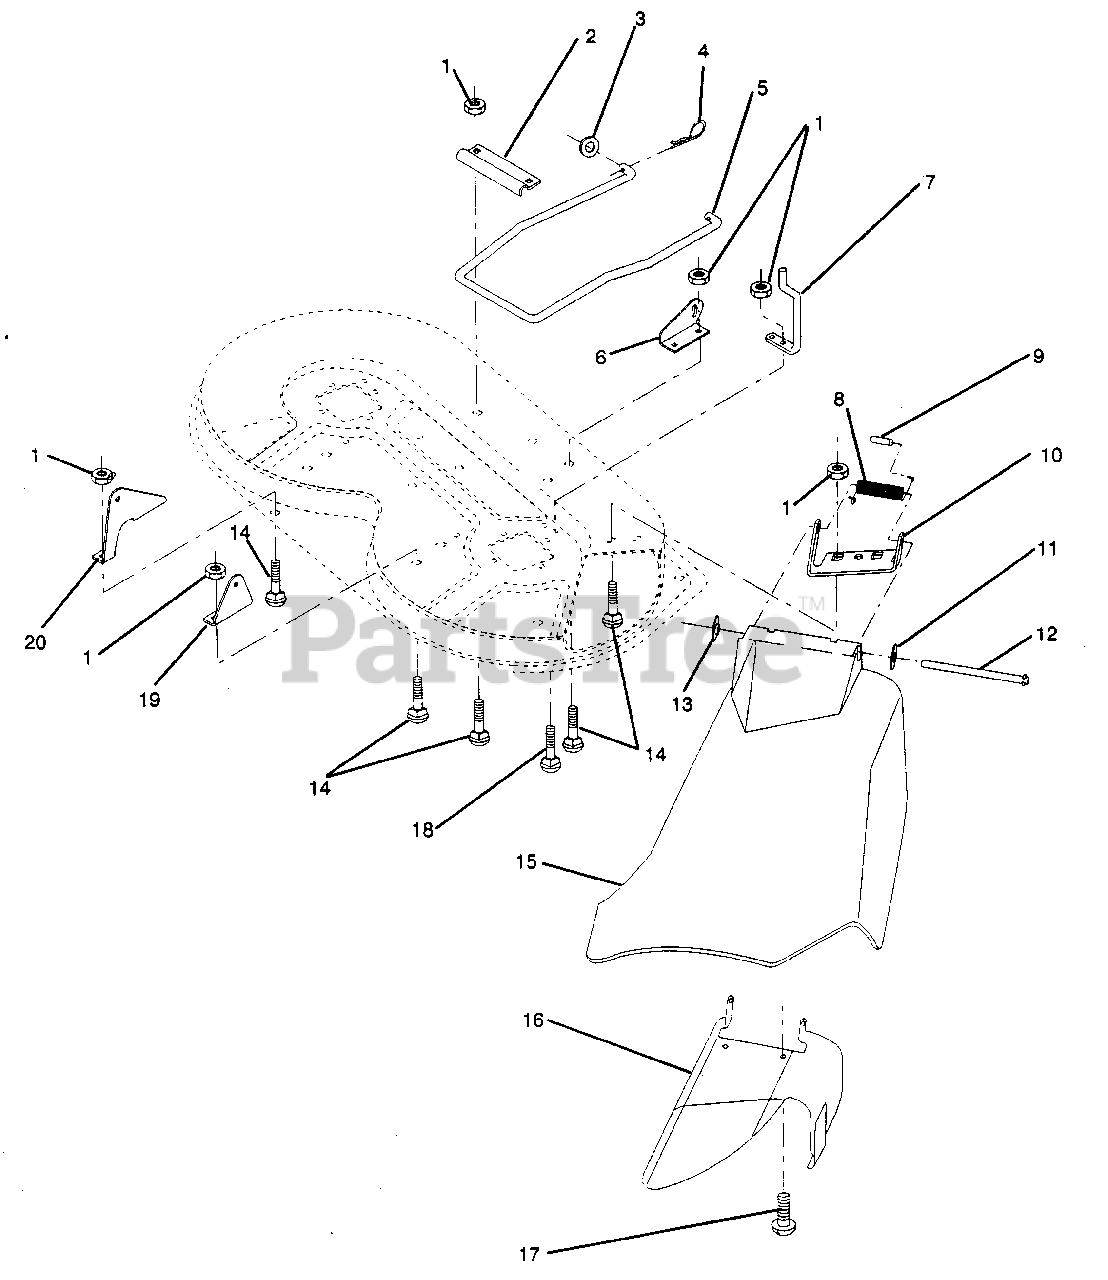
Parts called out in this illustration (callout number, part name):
1	Nut Crownlock 5/16-18
2	Bracket, Stabilizer Link (AYP part number)
3	Washer 17/32 x 1 1/16 x 13 Ga. (AYP part number)
4	Retainer, Spring (AYP part number)
5	Stabilizer, Mower Link (AYP part number)
6	Bracket, R.H. Front Lift (AYP part number)
7	Guide, Front Mandrel R.H. Mower Belt (AYP part number)
8	Spring, Torsion (AYP part number)
9	Cap, Sleeve (AYP part number)
10	Bracket, Deflector (AYP part number)
11	Washer 11/32 x 5/8 x 16 Ga. (AYP part number)
12	Rod, Hinge (AYP part number)
13	Pushnut (AYP part number)
14	Bolt, Carriage 5/16-18 UNC x 5/8 (AYP part number)
15	Guard, Discharge (AYP part number)
16	Assembly, Deflector Support (AYP part number)
17	Screw, Pan Hd. PLT-30 (AYP part number)
18	Bolt, Hex Head 5/16-18 UNC x 3/4 (AYP part number)
19	Bracket, R.H. Rear Lift (AYP part number)
20	Bracket, L.H. Rear Lift (AYP part number)
